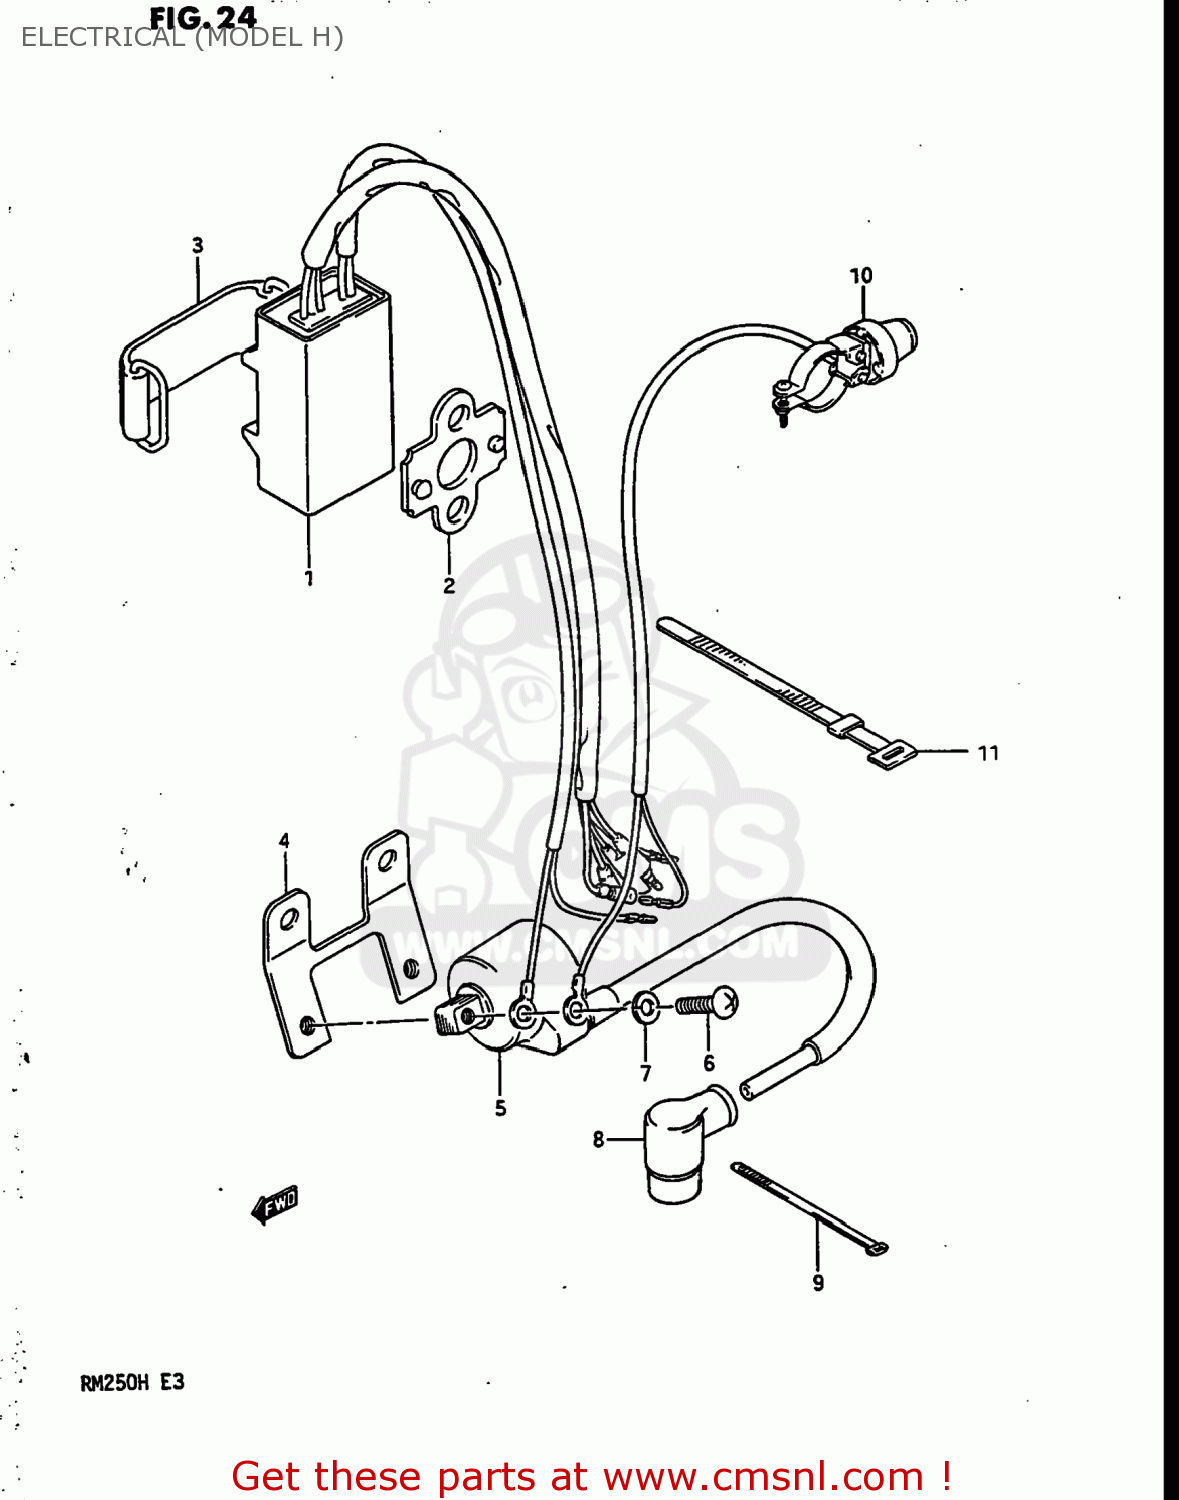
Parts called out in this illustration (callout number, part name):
1	UNIT,CDI
2	PROTECTOR,CDI UNIT
3	BAND
4	BRACKET,IGNITION COIL
5	COIL ASSEMBLY,IGNITION
6	SCREW
7	WASHER,LOCK
8	CAP,SPARK PLUG
9	CLAMP
10	SWITCH ASSEMBLY
11	CLAMP(L:120)
